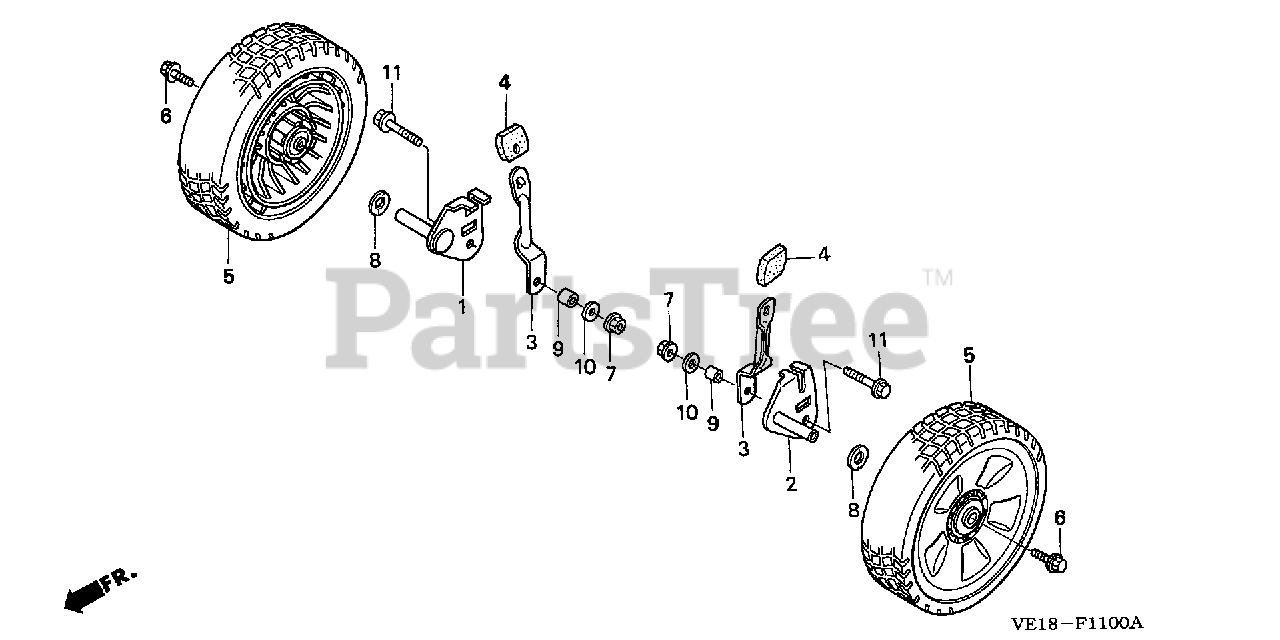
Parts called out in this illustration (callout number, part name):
1	ARM, R. FR. ADJUSTER
2	ARM, L. FR. ADJUSTING
3	PLATE, FR. ADJUSTER
4	GRIP, ADJUSTER
5	WHEEL *NH31* (MCKINLEY WHITE)
6	BOLT, WHEEL
7	NUT, SELF-LOCK (8MM) (CLINCH)
8	WASHER, WHEEL
9	COLLAR, FR. ARM
10	WASHER, PLAIN (8MM)
11	BOLT, FLANGE (8X50)
